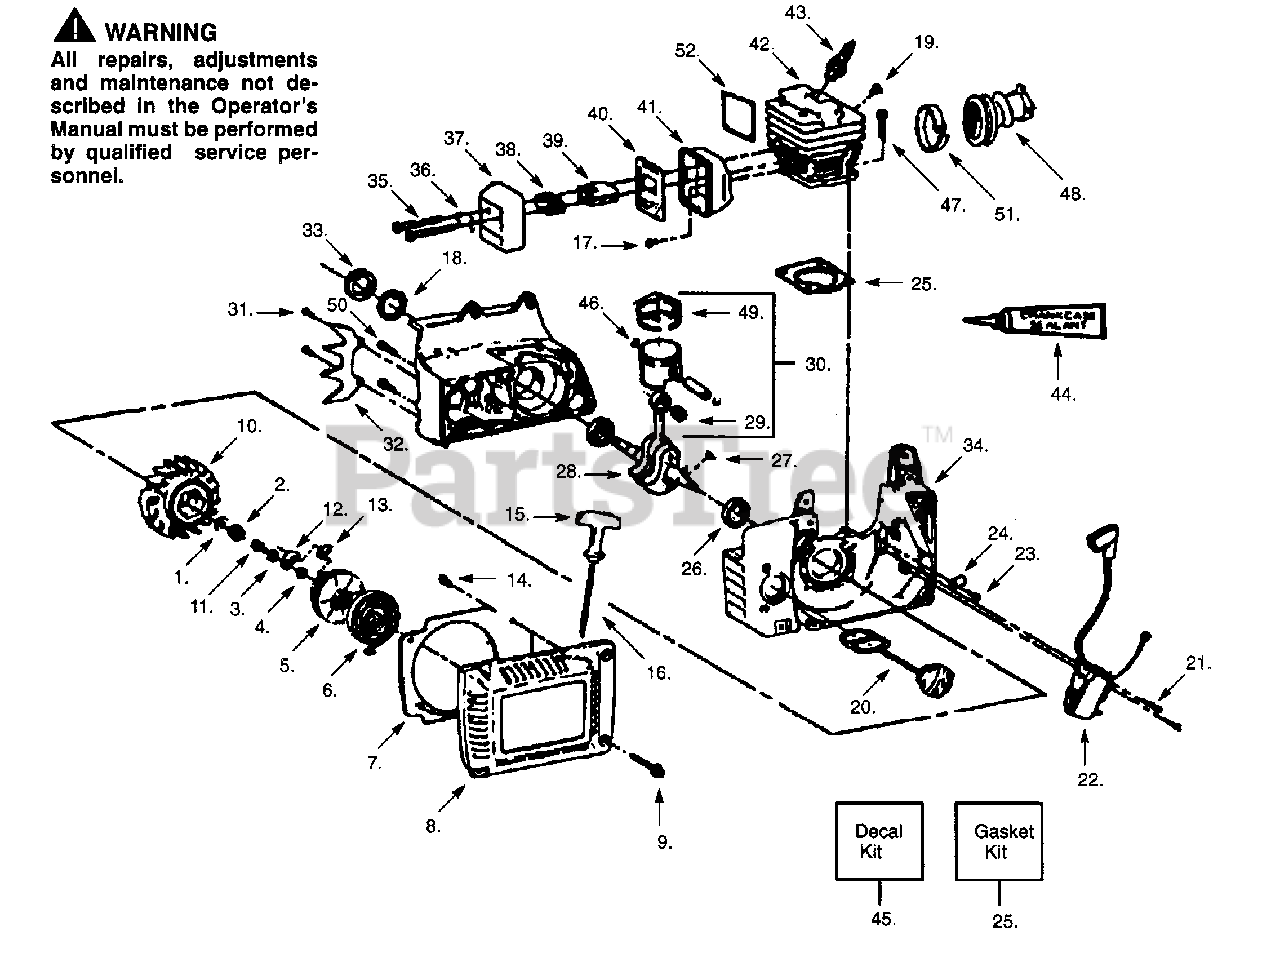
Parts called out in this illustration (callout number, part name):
1	Flywheel
3	Wave Washer
4	Retainer
5	Starter Pulley
6	Starter Spring
7	Baffle Plate
8	Fan Housing
9	Screw
12	Starter Cam
13	Starter Dog
15	Starter Handle
16	Rope Kit
18	Snap Ring
20	Oil Cap Ass'y. (Inc. O Ring)
21	Screw
22	Ignition Module
25	Gasket Set
26	Crankshaft Bearing
27	Flywheel Key
28	Crankshaft/Rod Ass'y.
29	Piston Pin Bearing
30	Model 285
30	Model 305
30	Model 335
33	Crankshaft Seal
34	Crankcase Assy
37	Muffler Cover
38	Spark Arrestor Screen
39	Muffler Diffuser
40	Muffler Baffle Plate
41	Muffler Body
42	Model 285
42	Model 305
42	Model 335
43	Spark Plug (CJ-4)
45	Decal Kit
46	Retainer
48	Carb. Adapter
49	Model 285
49	Model 305
49	Model 335
51	Clamp Ass'y.
52	Deflector (Model 335 Only)
